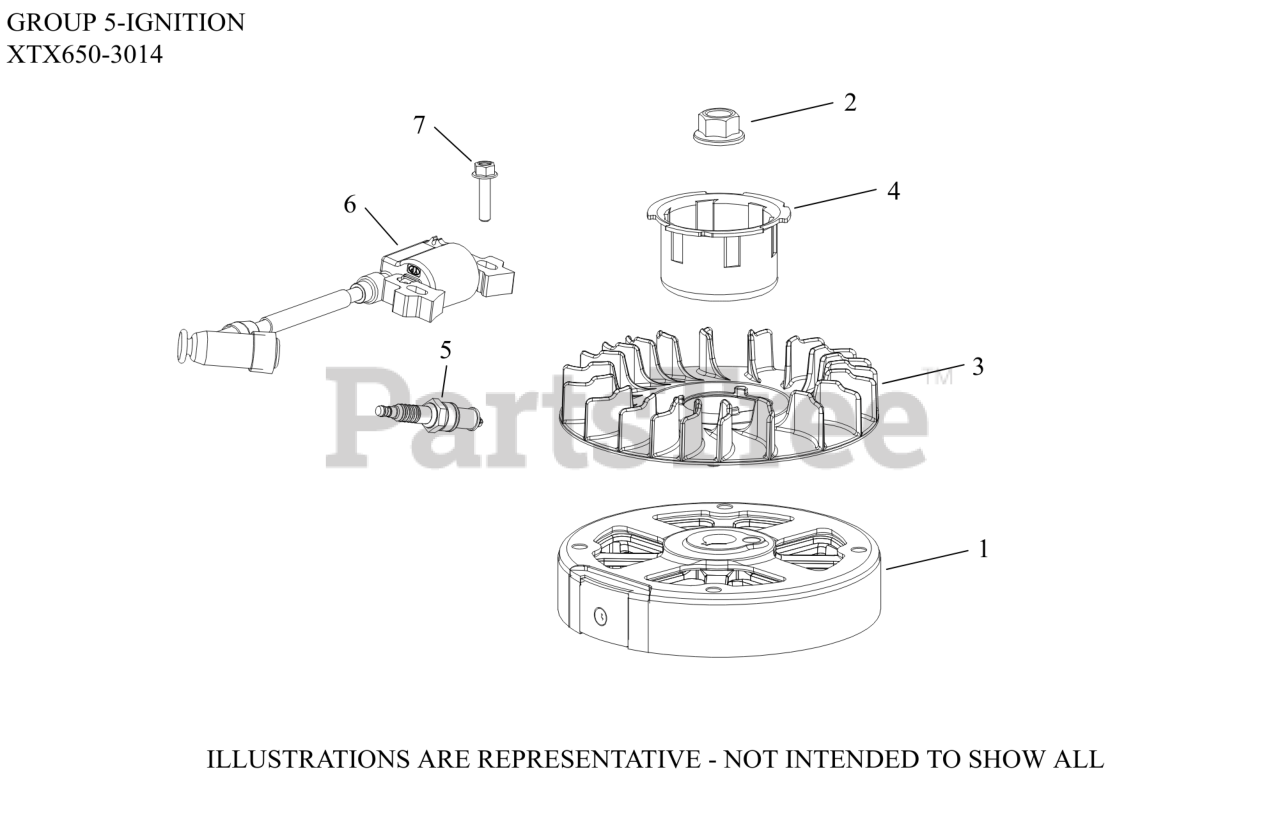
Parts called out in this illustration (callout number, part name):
1	FLYWHEEL ASSEMBLY
2	NUT, FLYWHEEL (W/SERRATIONS)
3	FAN, FLYWHEEL
4	CUP, STARTER DRIVE
5	PLUG SPARK 12MM RFI
6	MODULE IGN (#1458416S)
7	SCREW, M6 X 25-(#25086436S)
